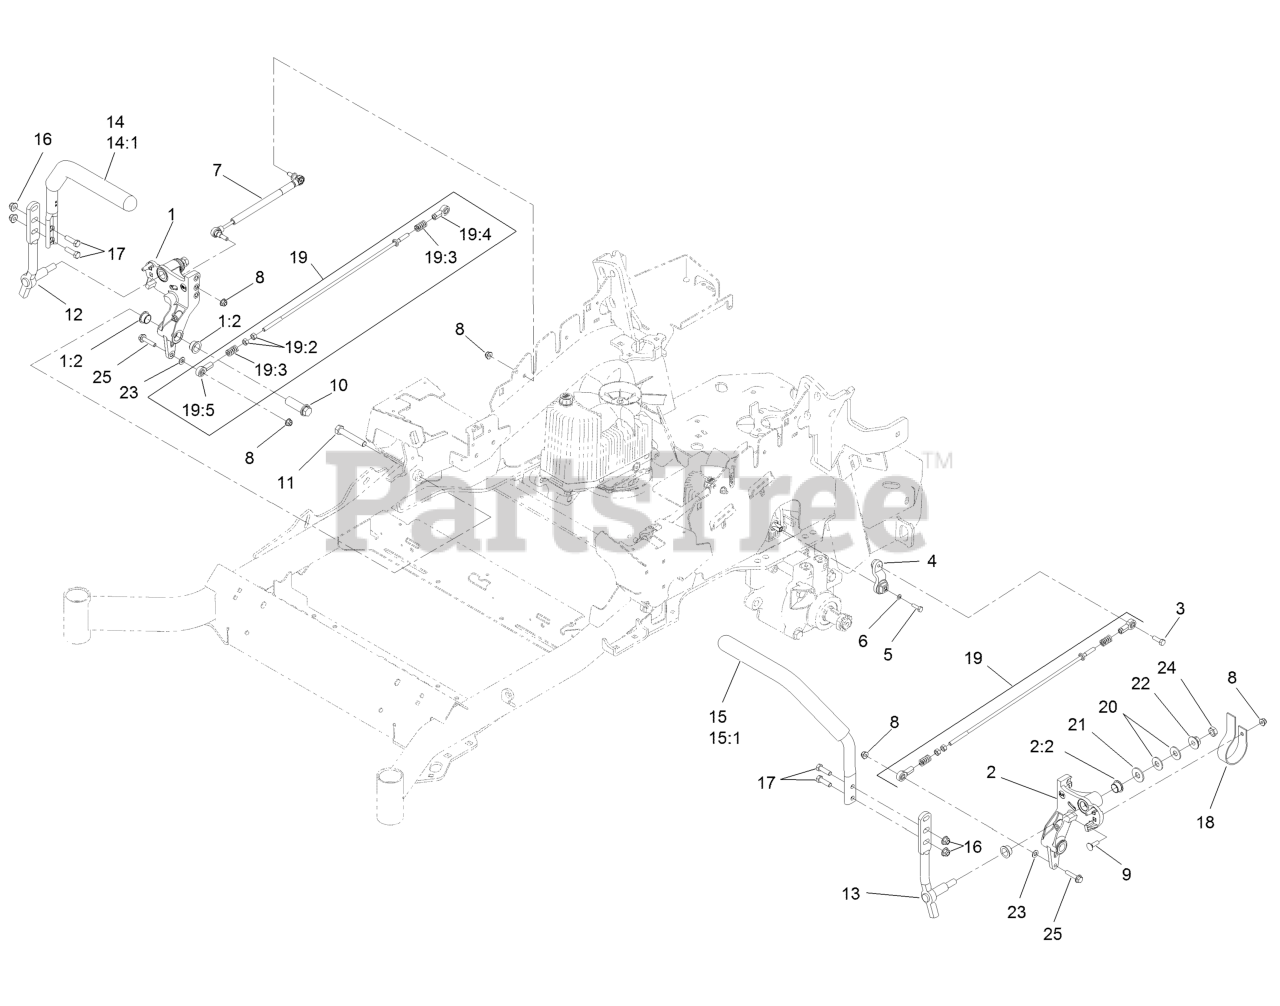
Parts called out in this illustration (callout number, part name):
1	RH Motion Control And Bushing ASM
1:2	Bushing-Flange
2	LH Motion Control And Bushing ASM
2:2	Bushing-Flange
3	Screw-HH, Thread Locking
4	Arm-Control, Pump
5	Screw-HH
6	Washer-Spring
7	Damper-Control, Motion
8	Nut-HF, NI
9	Bolt-CARR
10	Hub-Threaded
11	Screw-HH
12	Lever-Control Motion, RH
13	Lever-Control Motion, LH
14	RH Steering Handle ASM
14:1	Grip-Control, Lever
15	LH Steering Handle ASM
15:1	Grip-Control, Lever
16	Nut-HF, NI
17	Screw-HH
18	Spring-Leaf
19	Front Pump Linkage ASM
19:2	Nut-Hex
19:3	Spring-Compression
19:4	Balljoint-LH
19:5	Balljoint-RH
20	Washer-Spring
21	Washer-Flat
23	Washer-Plain
24	Nut-Jam
25	Screw-HHF
